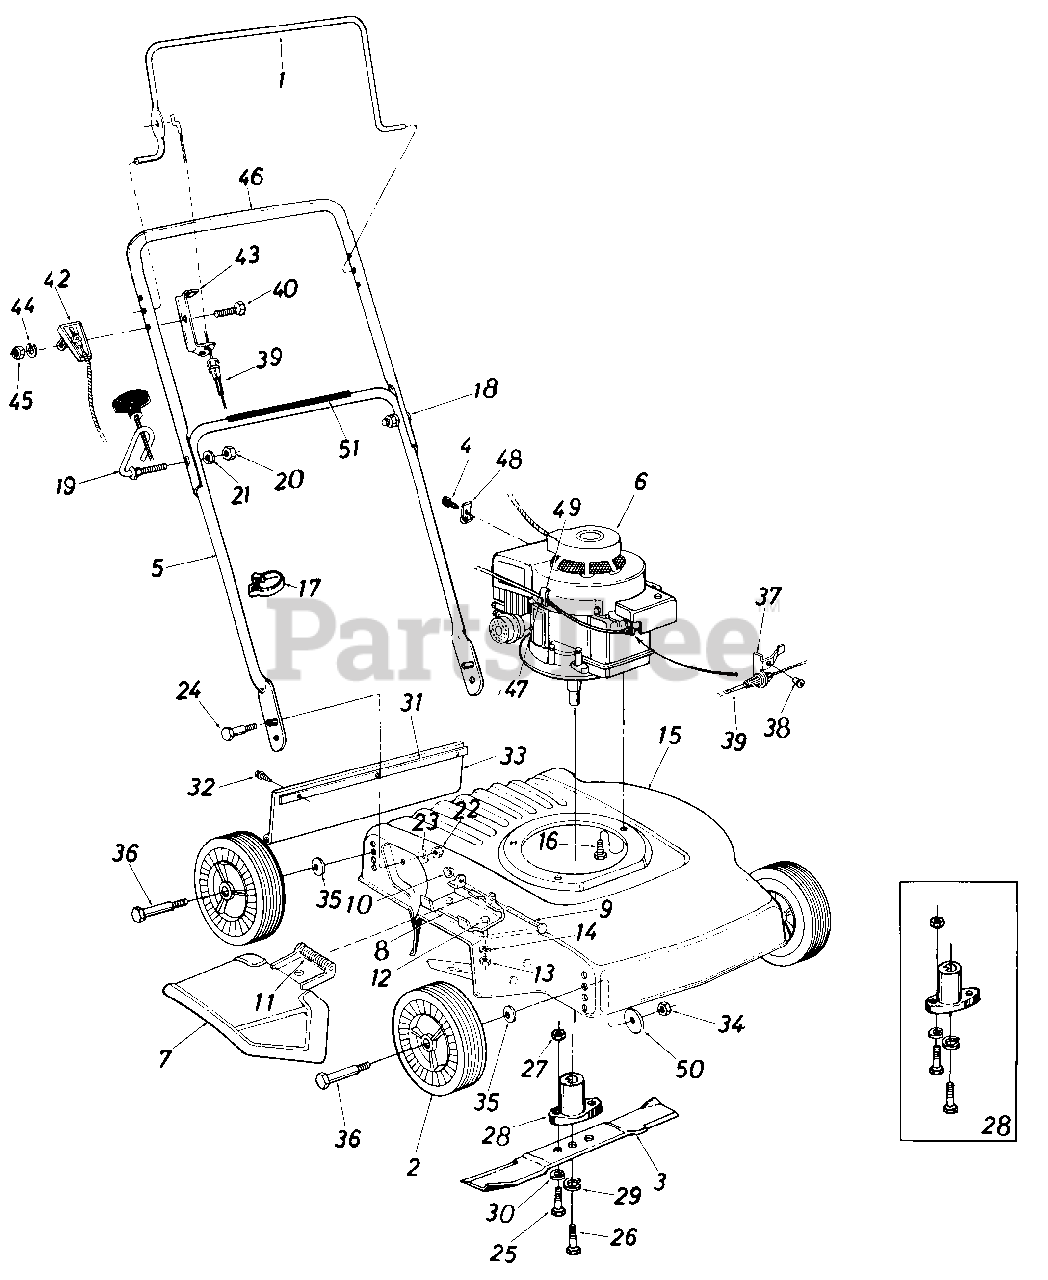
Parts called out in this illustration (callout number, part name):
1	Control Handle-R.H.
3	18" Blade
4	Hex Wash. Hd. AB-Tap Scr. #8 x .50" Lg.
5	Lower Handle (Chrome)
6	Engine
7	Chute Deflector Ass'y.-Comp.
8	Adapter Plate
9	Pivot Pin
10	Push Nut 1/4" Rod
11	Torsion Spring
12	Hex Bolt 1/4-20 x .50" Lg.*
13	Hex Nut 1/4-20 Thd.*
14	L-Wash. 1/4" I.D.*
15	18" Deck Ass'y.
16	Hex Wash. Hd. TT-Tap Scr. 3/8-16 x 1.00" Lg.
17	Cable Tie
18	Curved Carriage Bolt 5/16-18 x 1.38" Lg.
19	Rope Guide Bolt
20	Hex Nut 5/16-18 Thd.*
21	L-Wash. 5/16" I.D.*
22	Hex Ins. L-Nut 5/16-18 Thd.
23	Bell-Wash. .345" I.D. x .88" O.D.
24	Shoulder Bolt .437" Dia. x .180
25	Hex Bolt 5/16-24 x 1.00" Lg. (Grade 5)
26	Hex Bolt 3/8-24 x 2.25" Lg. (Grade 5)
27	Hex Nut 5/16-24 Thd.*
28	Blade Adapter Kit
29	L-Wash. 3/8" I.D.-H.D.
30	L-Wash. 5/16" I.D.*
31	Retaining Strip
32	Hex Wash. Hd. AB-Tap Scr. 1/4" x .62" Lg.
33	Rear Flap Ass'y.
34	Hex Nut 3/8-16 Thd.*
35	Bell-Wash. .400" I.D. x .88" O.D.
36	Shld. Bolt .498" Dia. x 1.450"
37	Cable Bracket
38	Pop Rivet .156" Dia. x .379
39	Control Cable-43"
40	Hex Bolt 1/4-28 x 1.75" Lg.
42	Throttle Control Ass'y.-Comp.
43	Cable Mounting Brkt.
44	L-Wash. 1/4" I.D.
45	Hex Nut 1/4 -28 Thd.
46	Upper Handle (Chrome)
47	Hex B-Tap Scr. #10 x .38" Lg.
48	Casing Clamp
49	Casing Clamp
50	Fl-Wash. .398" I.D. x 1.13"
51	Instruction Label-Handle
